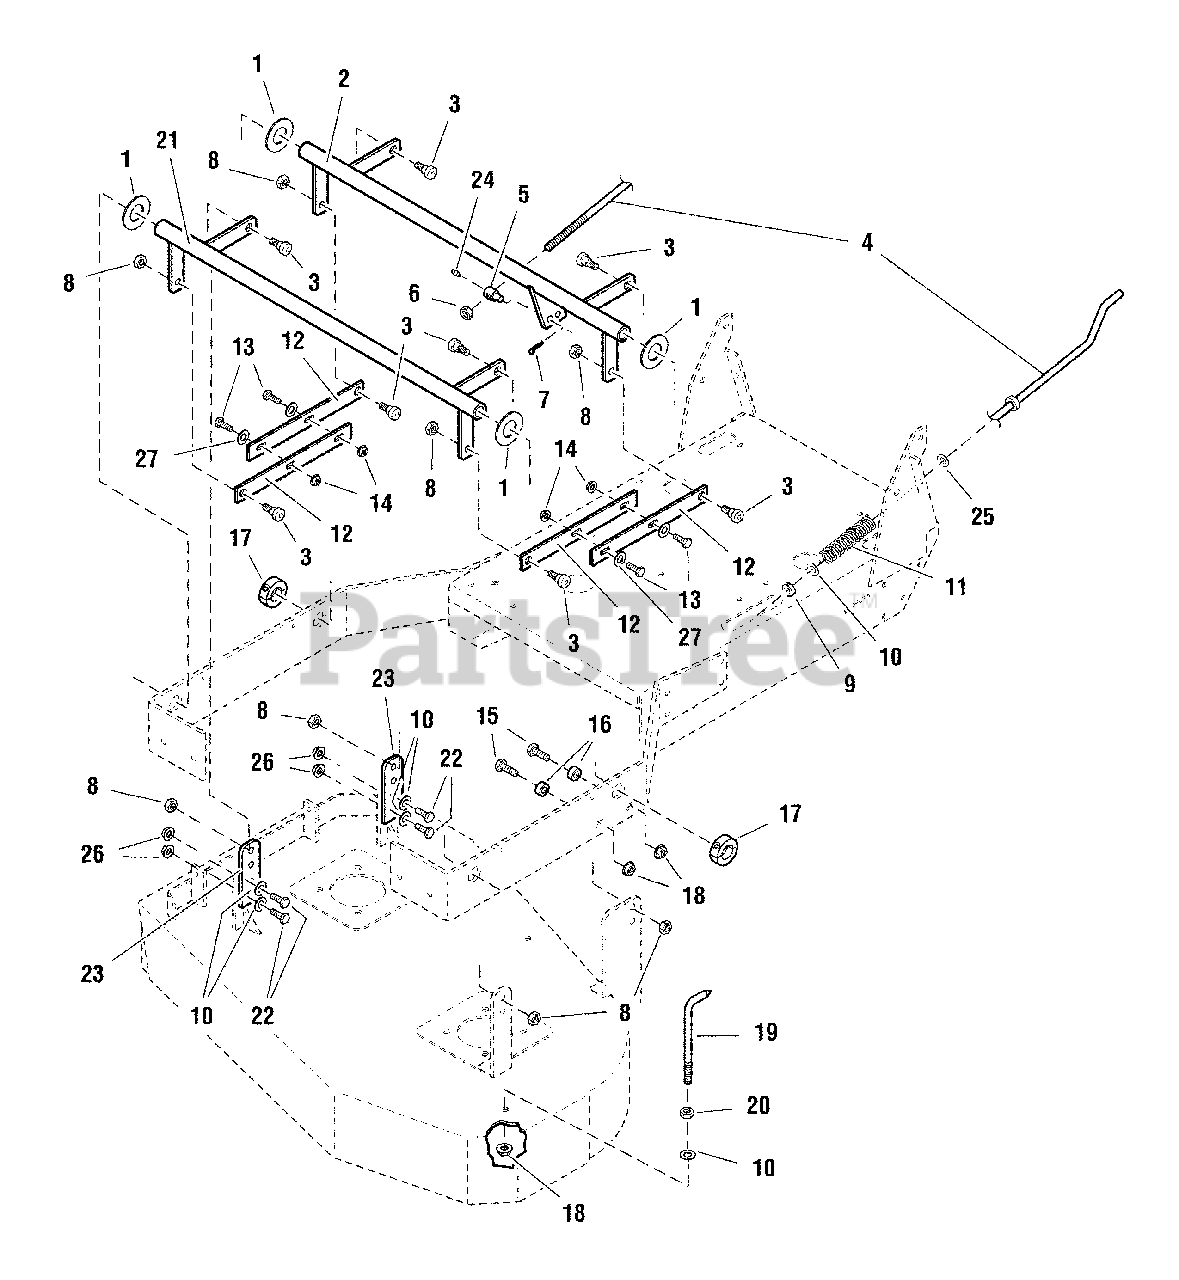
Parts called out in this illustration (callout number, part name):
1	WASHER-1.00 HYDRO CUT
2	WELD, DECK PIVOT, REAR
3	BOLT, 3/8-16 X 3/8, 1/2 SHOULDER
4	ROD CUTTER DECK HEIGHT CONTROL
5	LINKAGE, ADJUSTER
6	NUT, 3/8-16 HEX SIDE LOCK
7	PIN, COTTER, 3/32 X 3/4
8	NUT, 3/8-16, HEX TOP LOCK
9	COLLAR, 3/8 SET
10	WASHER, 3/8 SAE
11	SPRING, REVERSE RETURN
12	LINK, DECK ADJUST.
13	BOLT, 5/16-18 X 1 GD5 YZ
14	NUT, 5/16-18 HEX SERRATED FLANGE (LARGE)
15	BOLT, 3/8-16 X 1-1/4 GD5
16	SPACER, .39 X .75 X .38
17	COLLAR, 1" DOUBLE SPLIT
18	NUT, 3/8-16 HEX SERRATED FLANGE
19	POINTER, CUT HEIGHT
20	NUT, 3/8-16 HEX
21	DECK PIVOT WELDMENT, FRONT
22	BOLT, 3/8-16 X 1 GD5 YZ
23	HANGER, DECK
24	GREASE FITTING, 1/4-28 STRAIGHT
25	WASHER, 3/8" NYLON HYDRO CUT
26	NUT, 3/8-16 HEX NYLOCK FLANGE
27	WASHER, 5/16 GD.9 FLAT
